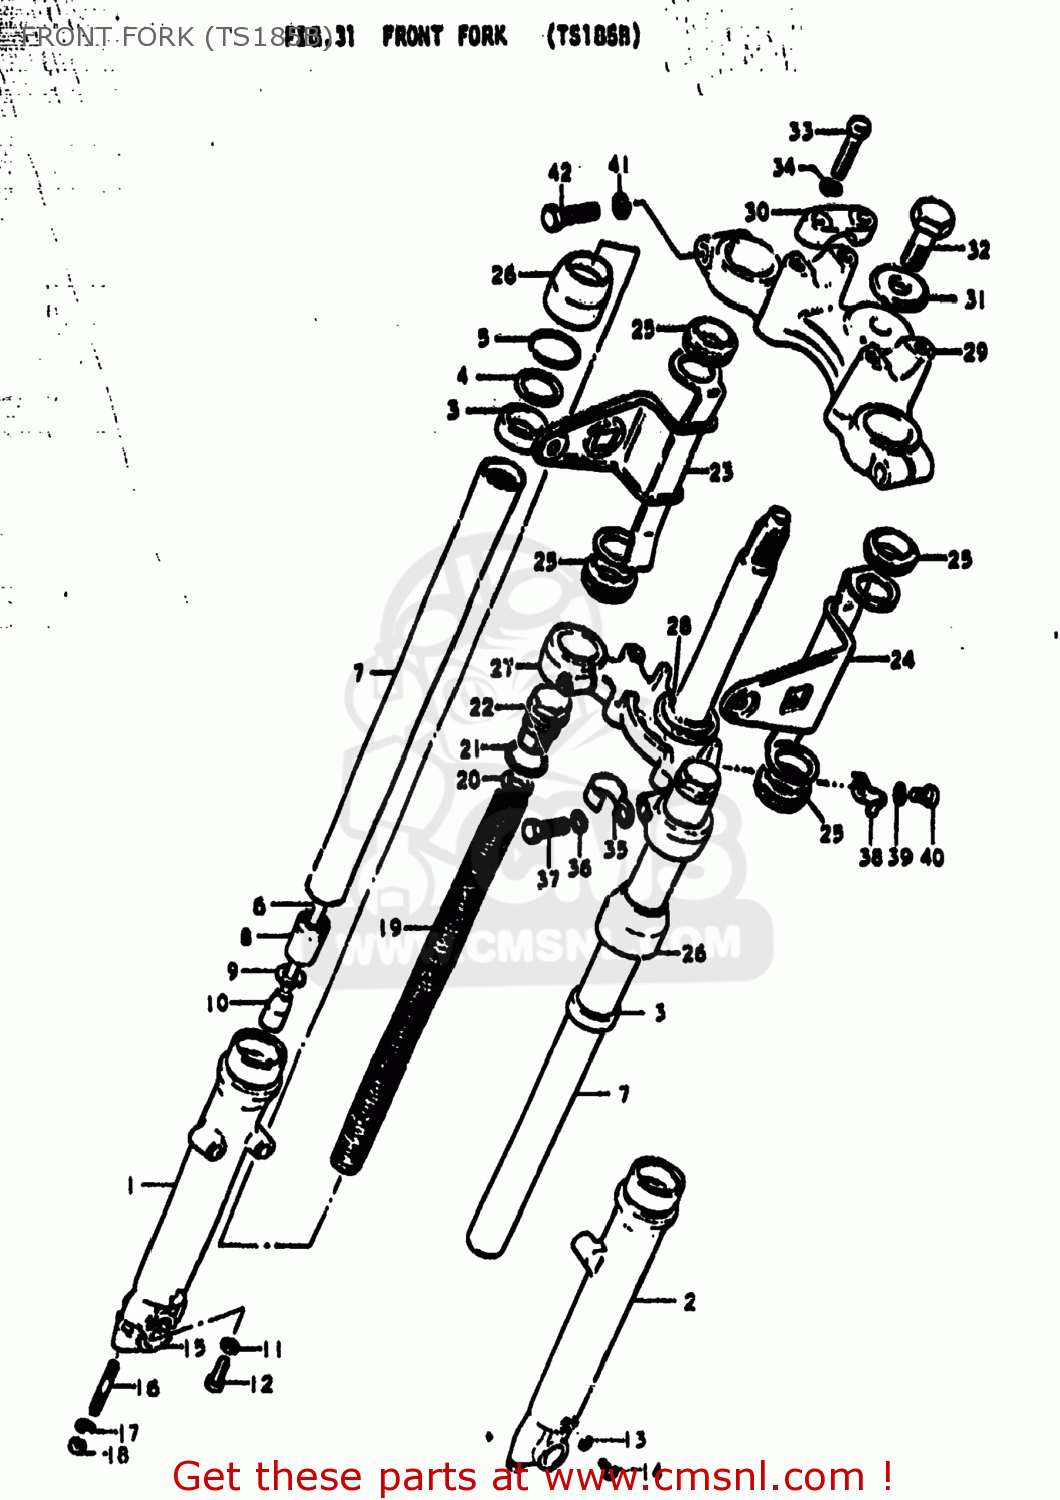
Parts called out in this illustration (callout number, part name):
0	DAMPER SET
1	TUBE,OUTER
2	TUBE,OUTER,LEFT
3	SEAL,OIL
4	WASHER,FRONT FORK
5	RING,SNAP
6	CYLINDER,FRONT FORK
7	TUBE,FORK,INNER
8	PISTON
9	SNAP RING
10	PIECE,OIL LOCK
11	GASKET (NAS)
12	BOLT
13	GASKET,DRAIN,PLUG (NAS)
14	SCREW
15	HOLDER,AXLE
16	STUD BOLT
17	LOCK WASHER
18	NUT (8MM)
19	SPRING
20	GUIDE,SPRING
21	O-RING,FORK INNER TUBE
22	BOLT,FR FORK
23	BRACKET,HEADLAMP HOUSING
24	BRACKET,HEADLAMP,LEFT
25	CUSHION,HEADLAMP BRACKET
26	SEAL,DUST
27	STEM,STEERING
28	RACE,STEERING OUTER LWR
29	HEAD,STEERING STEM
30	HOLDER,HANDLEBAR
31	WASHER,STEM HEAD(10.5X30X3.2)
32	BOLT,FORK INNER TUBE
33	BOLT
34	LOCK WASHER
35	CLIP
36	WASHER,LOCK 12
37	BOLT,FR FORK LWR(12X33)
38	CLIP
39	LOCK WASHER
40	SCREW
41	LOCK WASHER
42	BOLT,FORK INNER TUBE F
